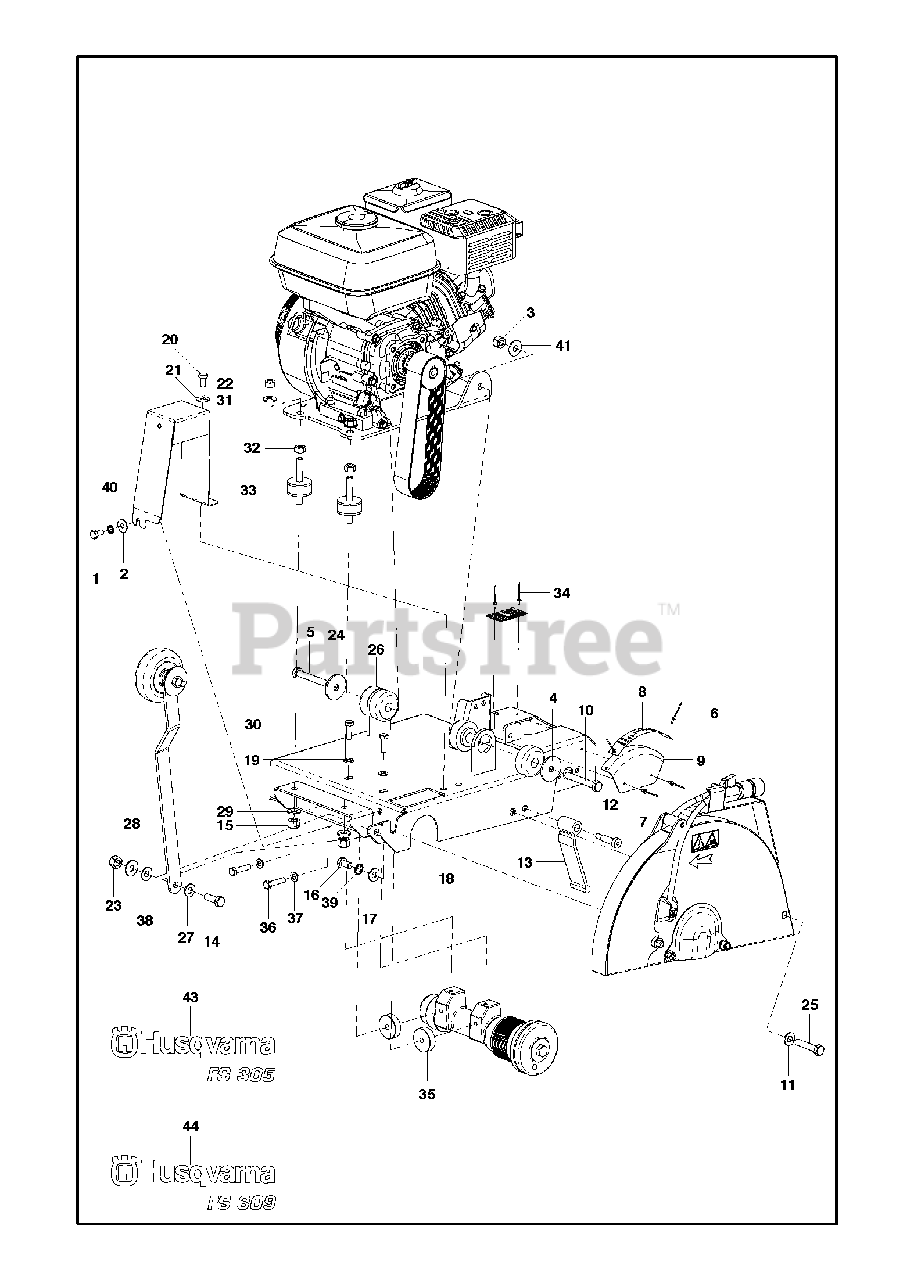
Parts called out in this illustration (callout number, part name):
1	SCREW EHHM
3	HEXAGON LOCKING NUT
11	WASHER
15	HEXAGON LOCKING NUT
17	WASHER
19	WASHER
20	SCREW EHHM
23	HEXAGON LOCKING NUT
27	WASHER
29	WASHER
31	WASHER
33	ANTIVIBRATION ELEMENT
37	WASHER
